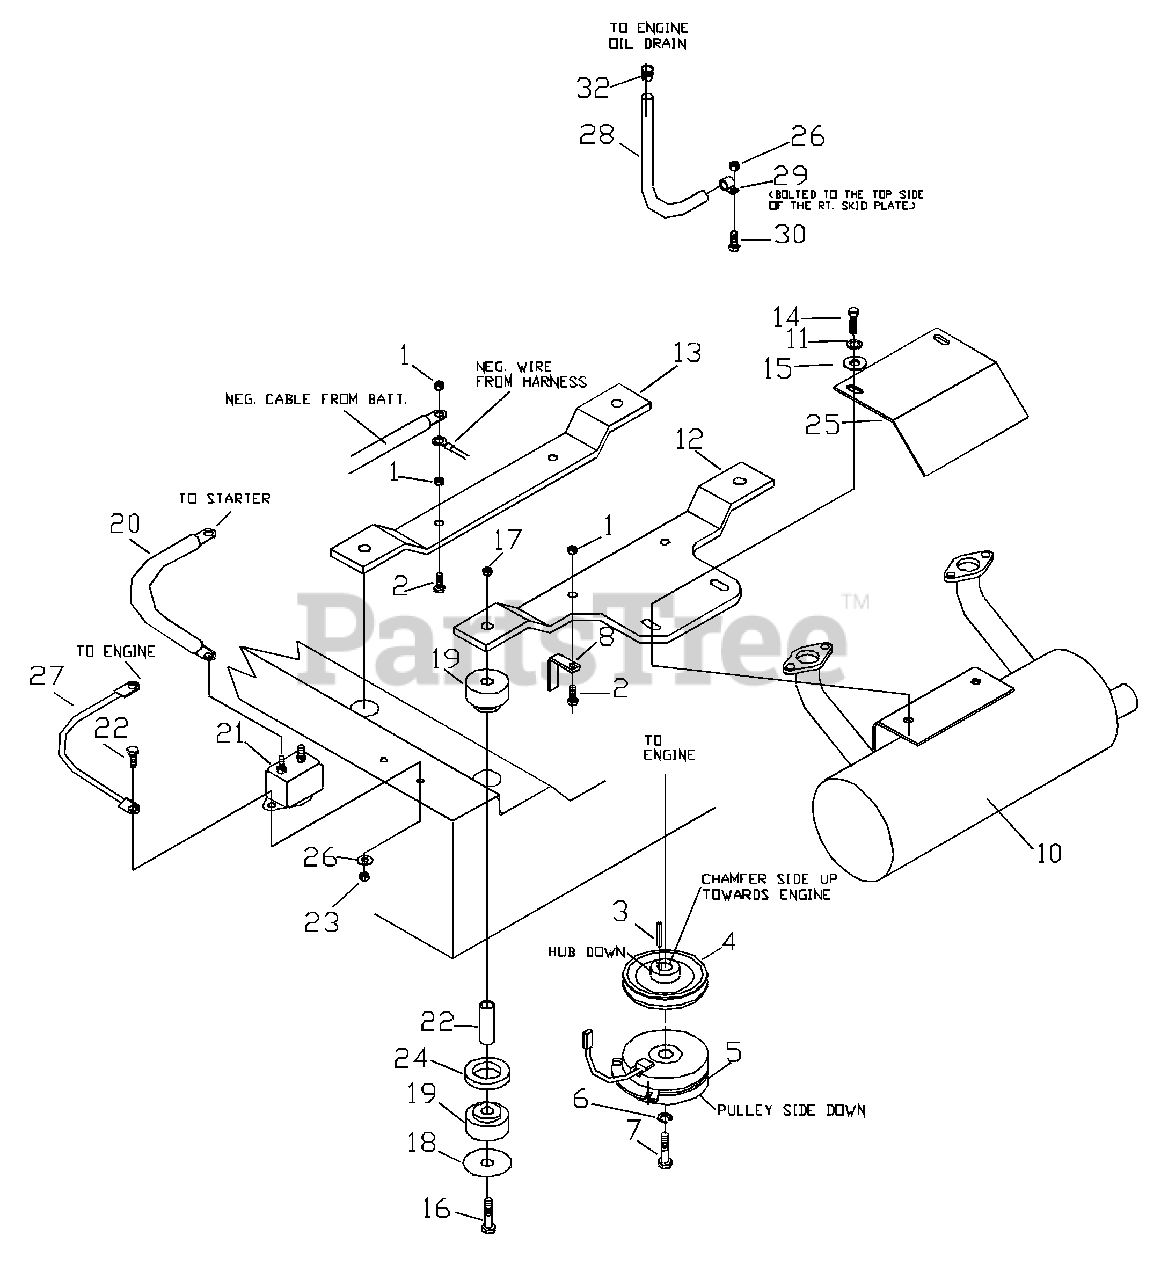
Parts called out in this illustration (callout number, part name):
1	NUT 5/16 LOCK
2	HCS 5/16 X 1.75
3	KEY 1/4 SQ.
6	WASHER 7/16 LOCK
7	HCS 7/16F X 2.5
8	CLUTCH TIE DOWN
9	KAWASAKI PIGTAIL
11	WASHER 5/16 LOCK
12	ENGINE MOUNT
13	ENGINE MOUNT
14	HCS 5/16 X .750
15	WASHER 5/16 FLAT
16	HCS 1/2 X 3.25
17	NUT 1/2 NYLOC
20	CABLE, POSITIVE
22	HCS 1/4 X .625
23	NUT 1/4 CTR. LOCK
25	MUFFLER GUARD
26	WASHER 1/4 INT. TOOTH
27	GROUND WIRE
28	OIL DRAIN HOSE
30	HCS 1/4 X .750
